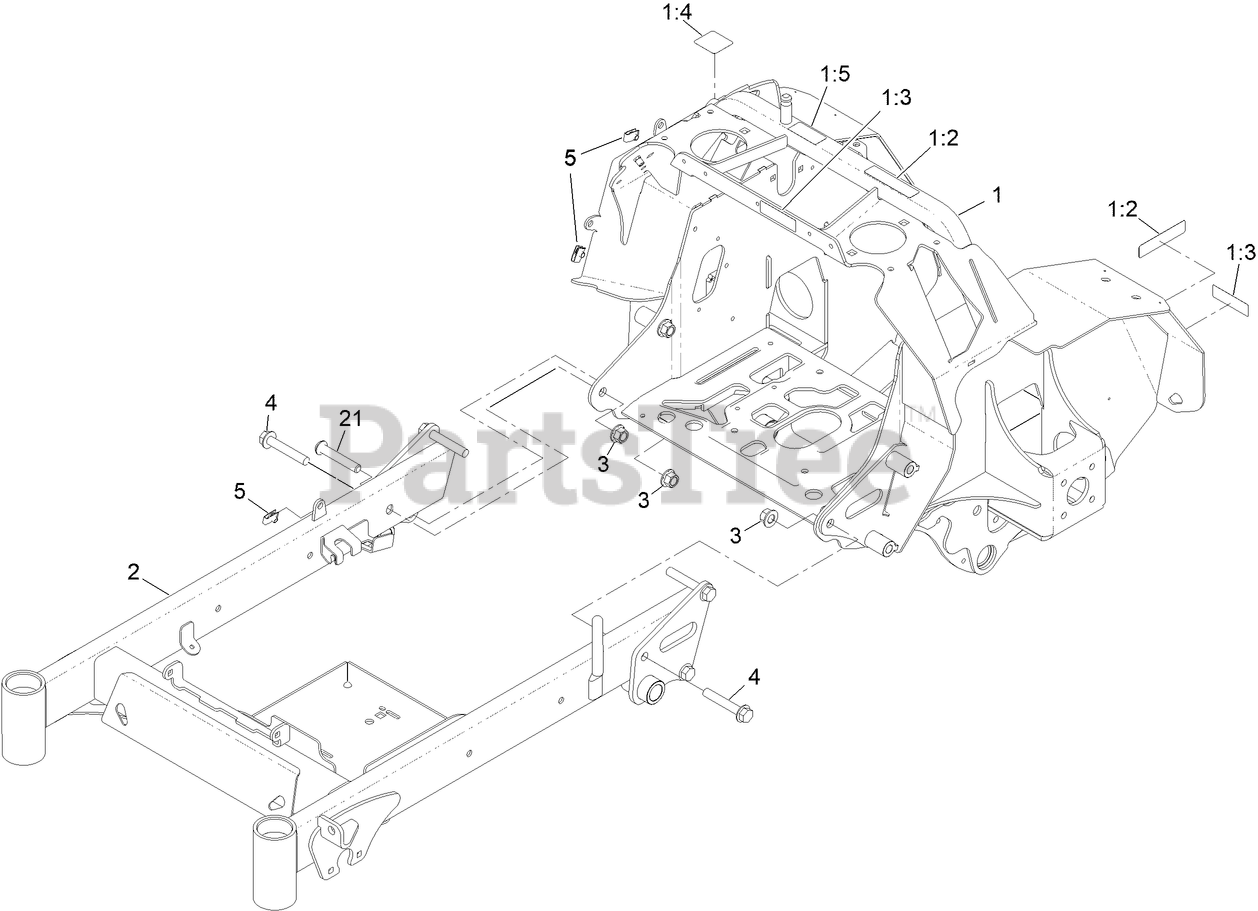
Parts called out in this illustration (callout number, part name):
1	ASM, REAR FRAME W/ DECALS
1:2	DECAL-WARNING
1:3	DECAL, COVER MISSING
1:4	DECAL-PARK BRAKE, CE
1:5	DECAL-BELT ROUTING HYD
2	ASM-FRONT FRAME W/DECAL
3	NUT-LOCK
4	SCREW-HF
21	SCREW, HSBH
